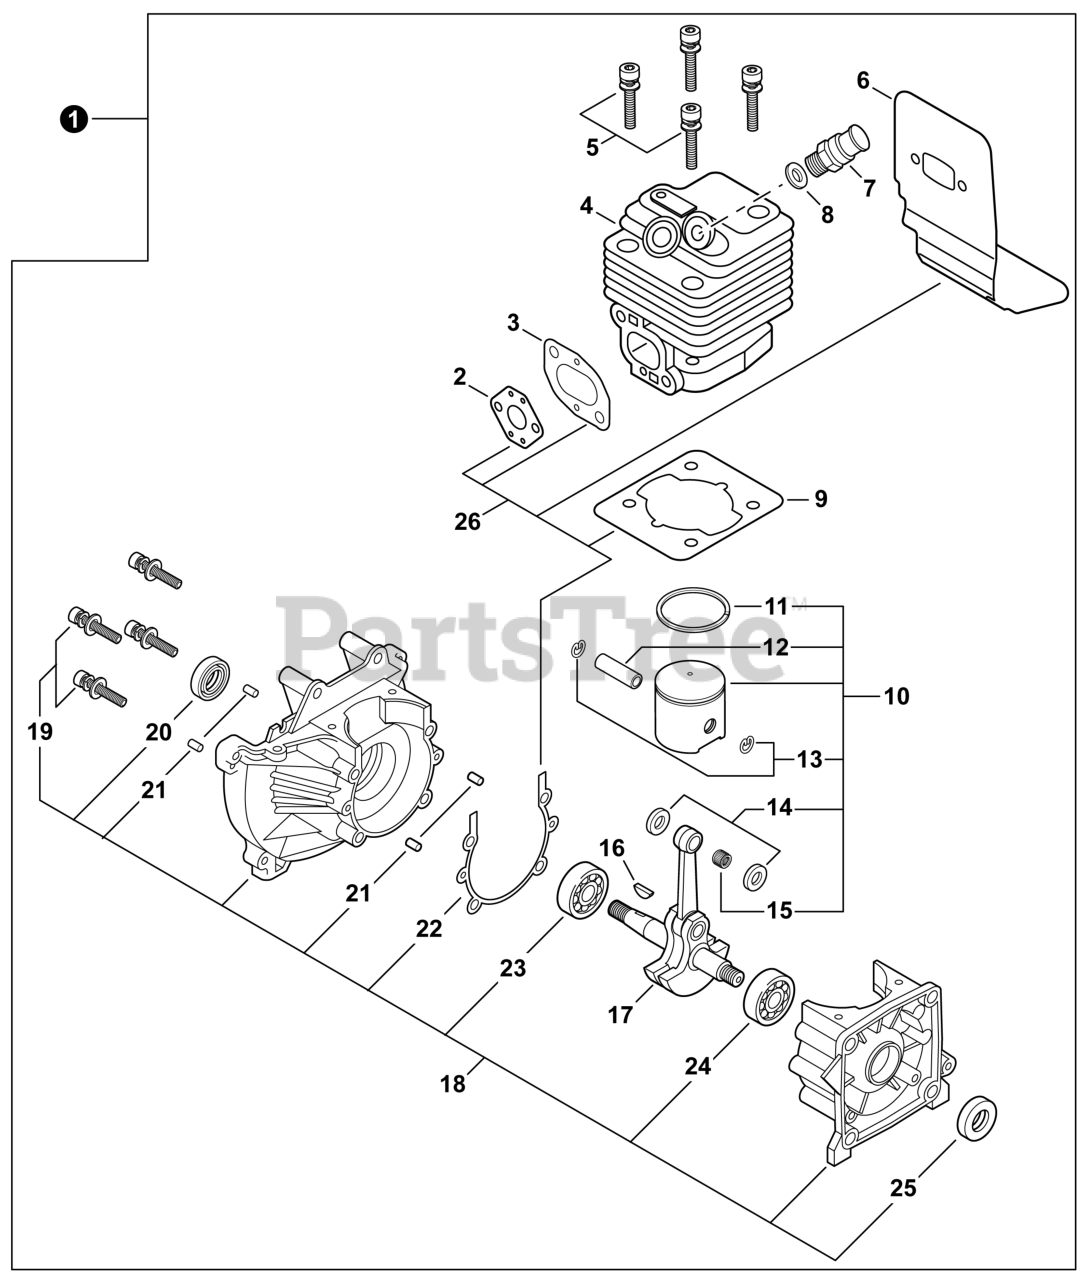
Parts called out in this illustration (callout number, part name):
1	SHORT BLOCK
2	GASKET, INTAKE
3	GASKET, INTAKE
4	CYLINDER
5	BOLT 5x20
6	HEAT SHIELD, EXHAUST
7	VALVE, DECOMPRESSION
8	GASKET, VALVE
9	GASKET, CYLINDER
10	PISTON KIT
11	RING, PISTON
12	PIN, PISTON 10
13	RING, SNAP 10
14	WASHER, THRUST
15	BEARING, NEEDLE 10
16	KEY, WOODRUFF 3x14
17	CRANKSHAFT ASSY
18	CRANKCASE KIT
19	BOLT M5x35
20	SEAL, OIL
21	PIN, LOCATING 4x8
22	GASKET, CRANKCASE
23	BEARING, BALL 6202
24	BEARING, BALL 6201
25	SEAL, OIL 12
26	GASKET KIT
